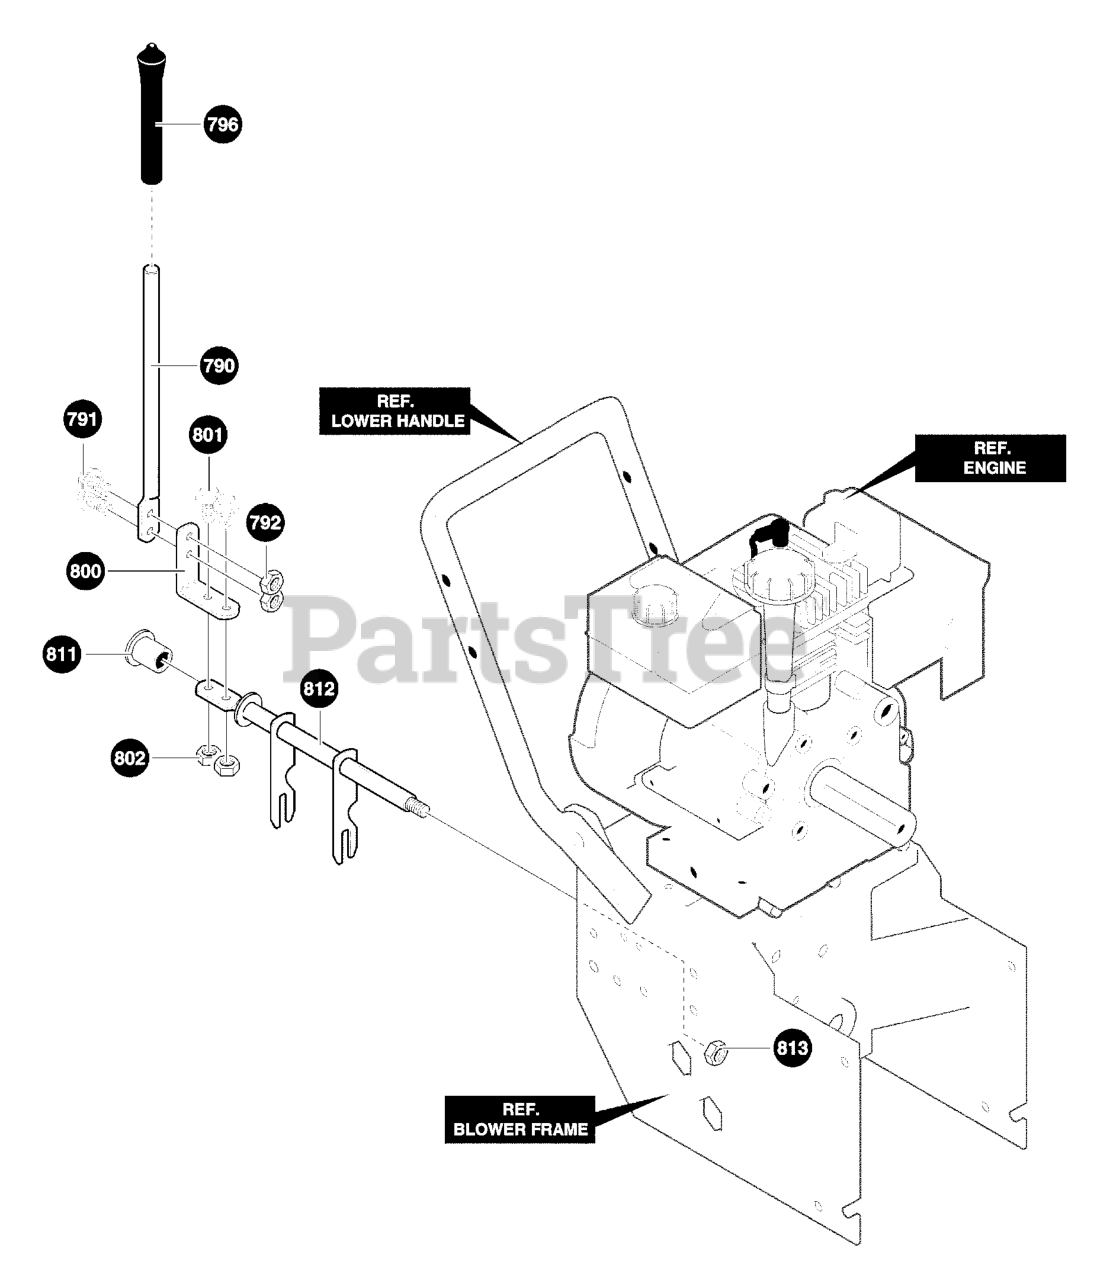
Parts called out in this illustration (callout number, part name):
790	ROD, SHIFT
791	SCREW, 1/4-20X.75
792	NUT, 1/4-20
796	KNOB, SLIP
800	LEVER, SPRING
801	SCREW, 1/4-20X.75
802	NUT, 1/4-20
811	BEARING, FLANGE
812	ROD, ASSY YOKE
813	NUT, 3/8-16
